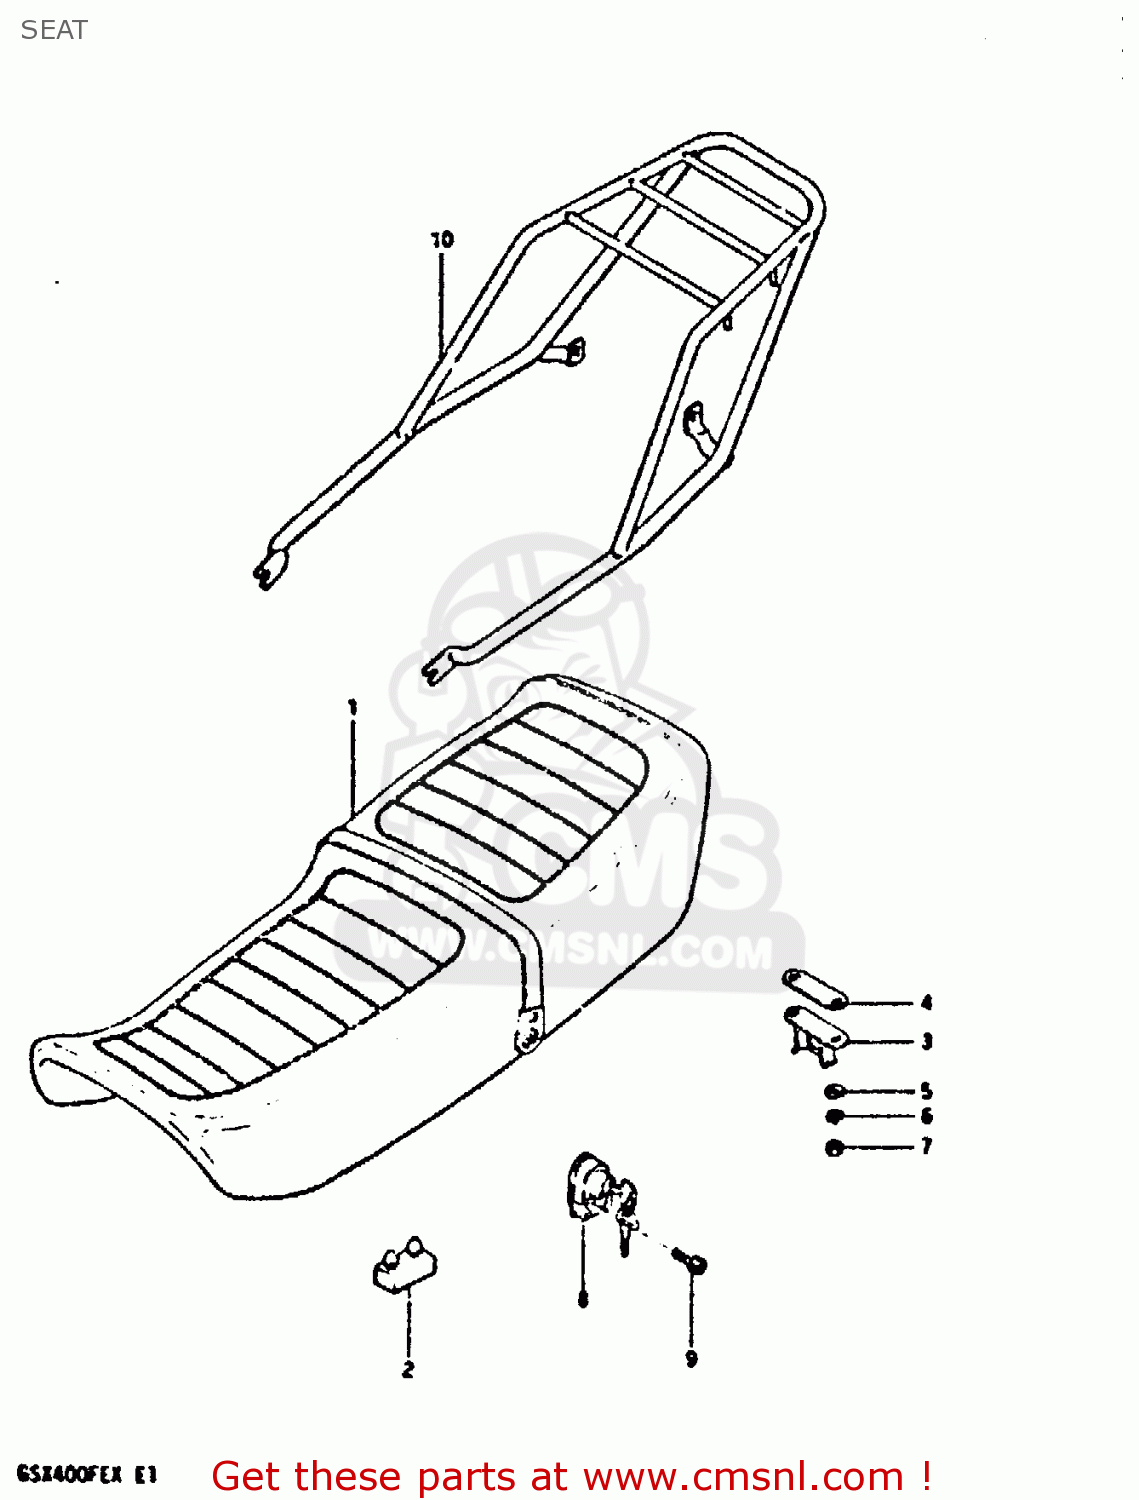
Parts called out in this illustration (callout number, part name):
1	SEAT ASSY (BLACK)
2	CUSHION
3	STRIKER,SEAT LOCK
4	SHIM,SEAT LOCK STRIKER
5	WASHER
6	LOCK WASHER
7	NUT 6MM
8	LOCK ASSY,HELMET
9	BOLT 5X25
10	CARRIER, SPORTS
